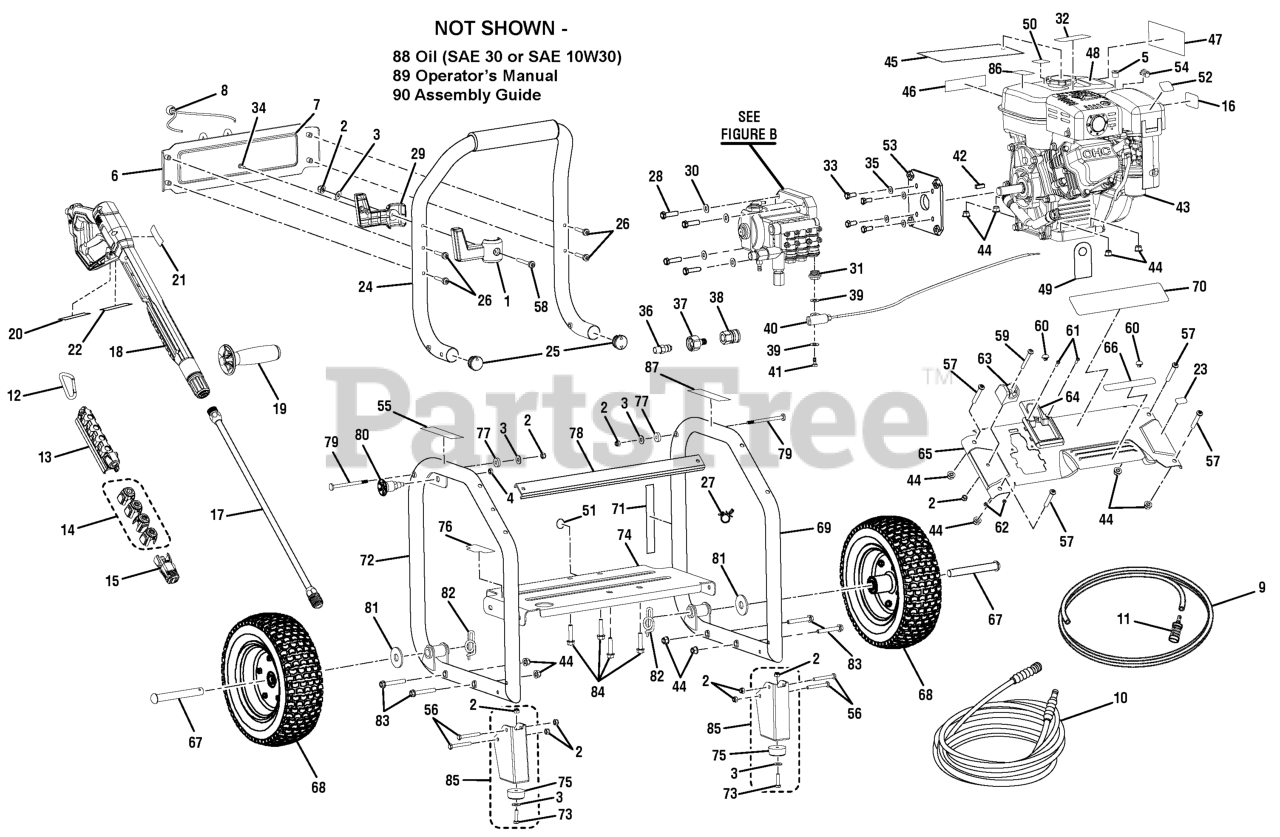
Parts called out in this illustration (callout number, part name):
1	WAND HOLDER (FRONT)
2	LOCK NUT (1/4-20)
3	WASHER (1/4 IN.)
4	LOCK NUT (1/2-20)
5	SWIVEL BUSHING
6	LOGO PLATE
7	PERFORMANCE LABEL
8	BUNGEE CORD AND BEAD ASSEMBLY
9	INJECTION HOSE
10	HIGH PRESSURE HOSE (30 FT.)
11	INJECTION HOSE FILTER
12	SPRING CLIP
13	STORAGE HOLDER
14	NOZZLE KIT
15	SOAP BLASTER NOZZLE
16	SQUEEZE TRIGGER LABEL
17	SPRAY WAND
18	TRIGGER HANDLE ASSEMBLY
19	AUXILIARY HANDLE ASSEMBLY
20	TRIGGER GUARD WARNING LBL F/S
21	TRIGGER GUARD WARNING LABEL
22	MAX PRESSURE LABEL
23	IDLE CONTROL LABEL
24	HANDLE ASSEMBLY
25	HANDLE TUBE CAP
26	BOLT (1/4 X 42 MM, PAN HD.)
27	CABLE CLAMP
28	BOLT (3/8-16 X 1-3/8 IN HEXHD)
29	WAND HOLDER (BACK)
30	WASHER (3/8 IN.)
31	THREADED VALVE PLUG
32	DO NOT MIX LABEL
33	BOLT (5/16-24 X 3/4 IN HEX HD)
34	SCREW (#8)
35	WASHER (5/16 IN.)
36	THERMAL RELEASE VALVE
37	GARDEN HOSE COUPLER W/FILTER
38	QUICK DISCONNECT (FEMALE)
40	THROTTLE CONTROL ASSEMBLY
41	THROTTLE CONTROL BOLT(SPECIAL)
42	OUTPUT SHAFT KEY (27 MM)
43	SP210 HORI. ENGINE (Parts available at your local Subaru dealer)
44	LOCK NUT (M8 X 1.25 MM)
45	HANG TAG (ENGINE)
46	ADD LUBRICANT LABEL
47	COMBUSTION WARNING LABEL
48	DANGER LABEL (ENGINE)
49	OIL DIPSTICK HANG TAG
50	E-85 LABEL
51	CHECK OIL LABEL
52	HOT MUFFLER LABEL
53	PUMP FLANGE
54	CABLE CLAMP
55	HANDLE RELEASE LABEL
56	BOLT (1/4-20 X 52 MM HEX HD.)
57	BOLT (M8 X 70 MM HEX SOC. HD.)
58	SCREW (1/4-20 X 2.27 IN.)
59	SCREW (1/4-20 X 2.1 T30 TORX)
60	BUMPER HANDLE
61	SCREW (M4 X 12 MM HEX BUTN HD)
62	LOCK NUT (M4)
63	WAND HOLDER
64	TRIGGER HANDLE STORAGE
65	FACE PLATE
66	HOT SURFACE LABEL
68	WHEEL (D12 IN. X 3 IN.)
69	LEFT FRAME
70	LOGO LABEL
71	QUICK START LABEL (ENGINE)
72	RIGHT FRAME ASSEMBLY
73	BOLT (1/4-20 X 1 IN.)
74	ENGINE PLATE
75	WEAR PAD
76	QUICK START LABEL (PUMP)
77	WASHER (OD20 X ID8 X 4.5T)
79	CONNECTOR PIN (1/4 IN.)
80	HANDLE KNOB
81	WASHER (5/8 IN.)
82	HITCH PIN
83	BOLT (M8 X 55 MM HEX HD.)
84	BOLT (M8 X 45 MM HEX HD.)
85	FOOT ASSEMBLY
86	DANGER LABEL (FRENCH)
87	EMC LABEL
